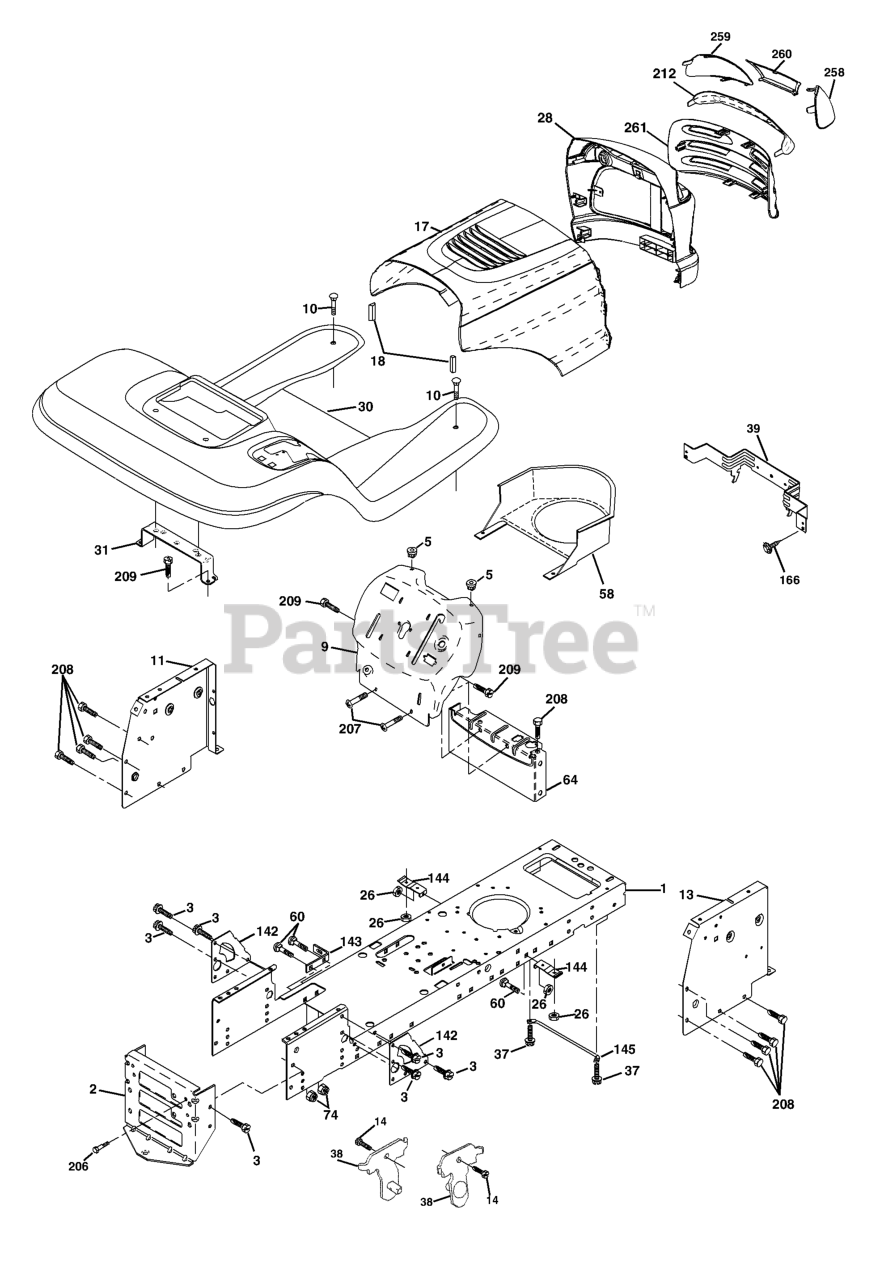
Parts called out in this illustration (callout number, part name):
1	CHASSIS STAMPING
2	DRAWBAR, 12GA
3	SCREW 3/8-16X3/4
5	BUMPER.RUBBER.HOOD
9	DASH
10	BOLT D
11	PANEL.DASH.LH.LTX
13	PANEL DASH RH
14	SCREW LT
17	HOOD
18	BUMPER.HOOD.LARGE.1.75"
26	NUT
28	GRILL/LEN.ASM.DL.HUSQ
30	FENDER FOOTREST
31	BRACKET.SUPPORT.FENDER
37	Screw Thdrol 5/16-18 x 1/2
38	BRACKET.ASM.PIVOT.MOWER.REAR
39	BRACKET PIVOT LASER
58	AIR DUCT P/L/LT
60	Bolt RDHD SQNK 3/8-16 x 3/4
64	DASH LOWER
142	PLATE REINFORCEMENT
143	BRACKET, SWAY BAR
144	BRKT, FOOT REST
145	ROD PIVOT CHASSIS/HOOD
166	SCREW
206	SHOULDER BOLT 5/16-18TT
207	SCREW, 5/16-18 X 1/2
208	SCREW 3/8-16X1/2
209	SCREW, 3/8-16X3/4
212	INSERT.LENS.REFLECTIVE
258	LENS LH
259	LENS LH
260	COVER.LENS.HUSQ.( HAVE GRAY)
261	INSERT GRILLE
